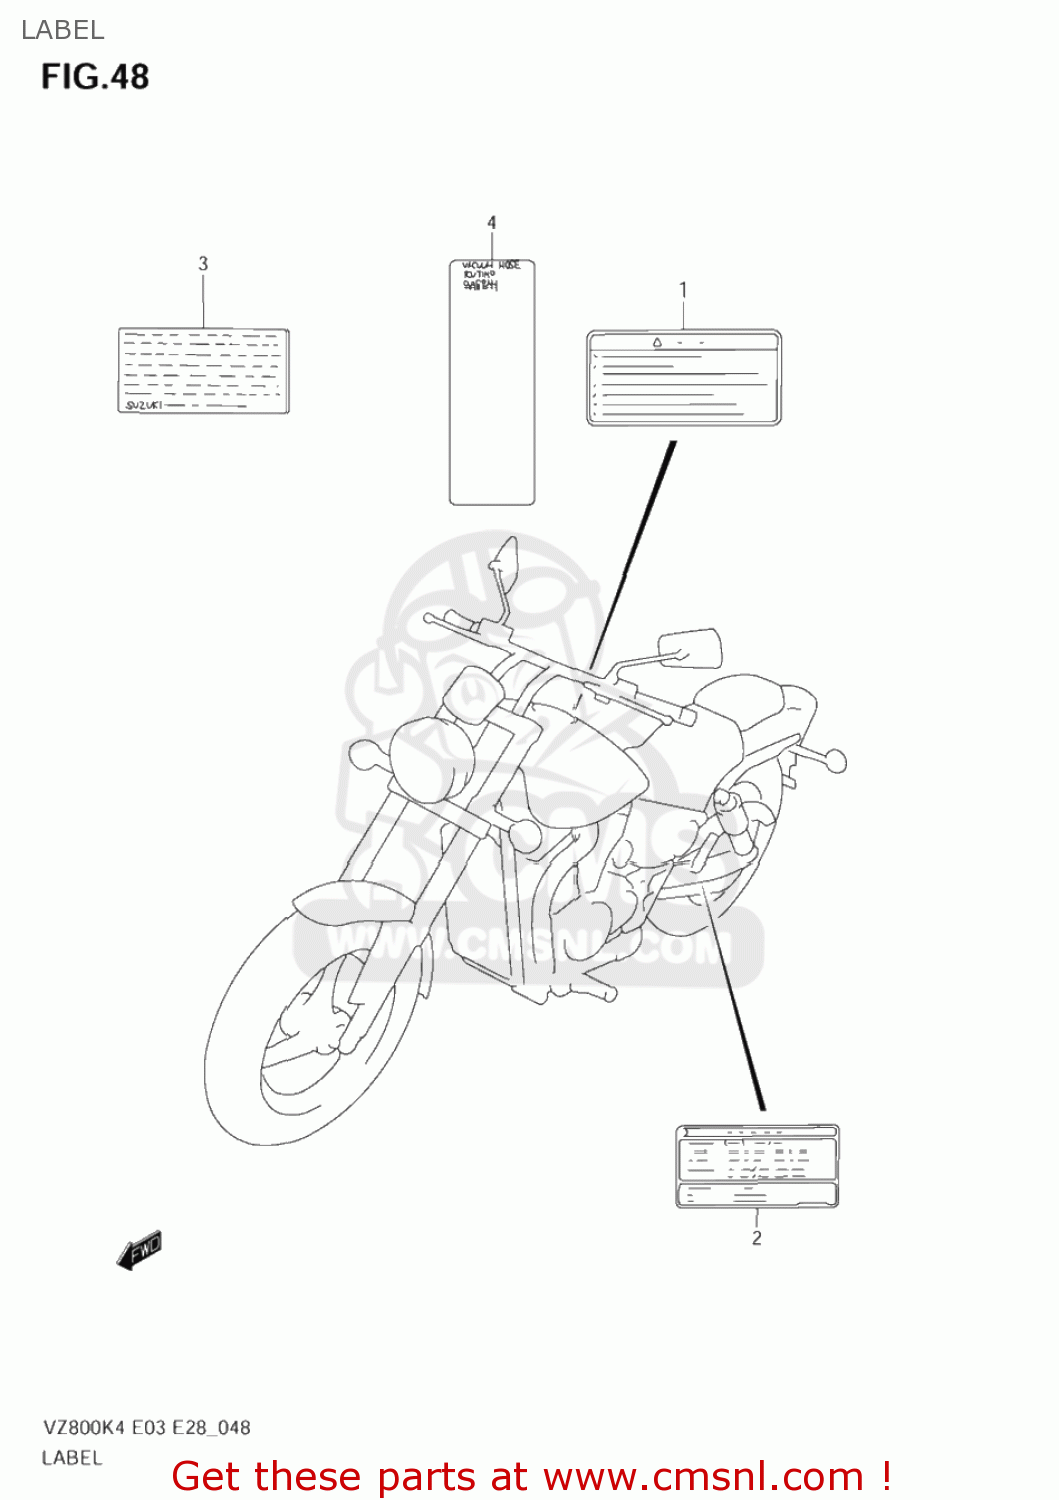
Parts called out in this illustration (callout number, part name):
1	LABEL,GENERAL WARNING
2	LABEL, TIRE INFORMATION
3	LABEL,MANUAL NOTICE
4	LABEL,ROUTING
5	MANUAL,OWNER'S
